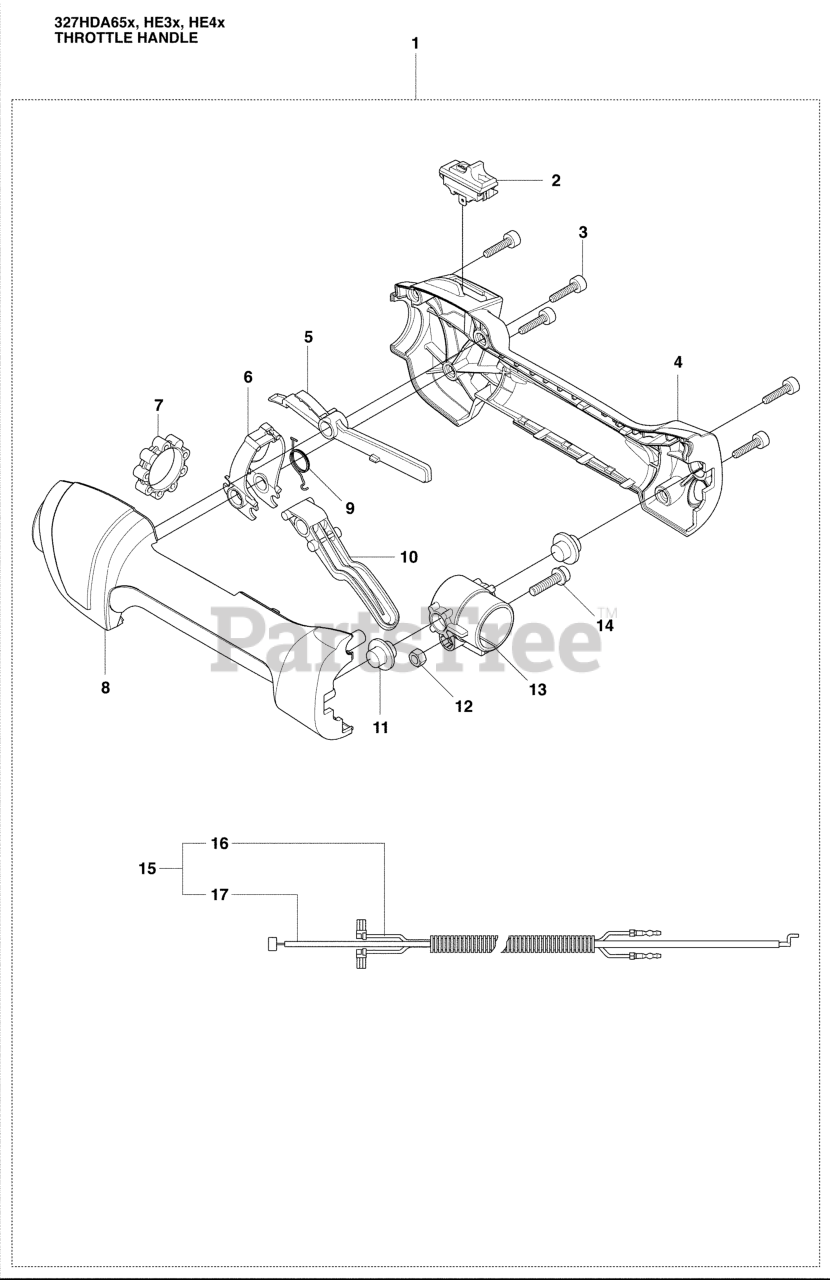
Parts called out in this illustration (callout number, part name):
1	ASSY THROTTLE CONTROL
2	STOP BUTTON
5	THROTTLE LOCK
7	VIBRATION DAMPER
9	RETURN SPRING
10	THROTTLE TRIGGER
11	VIBRATION ABSORBER
16	SHORT CIRCUIT CABLE
17	THROTTLE WIRE ASSY
